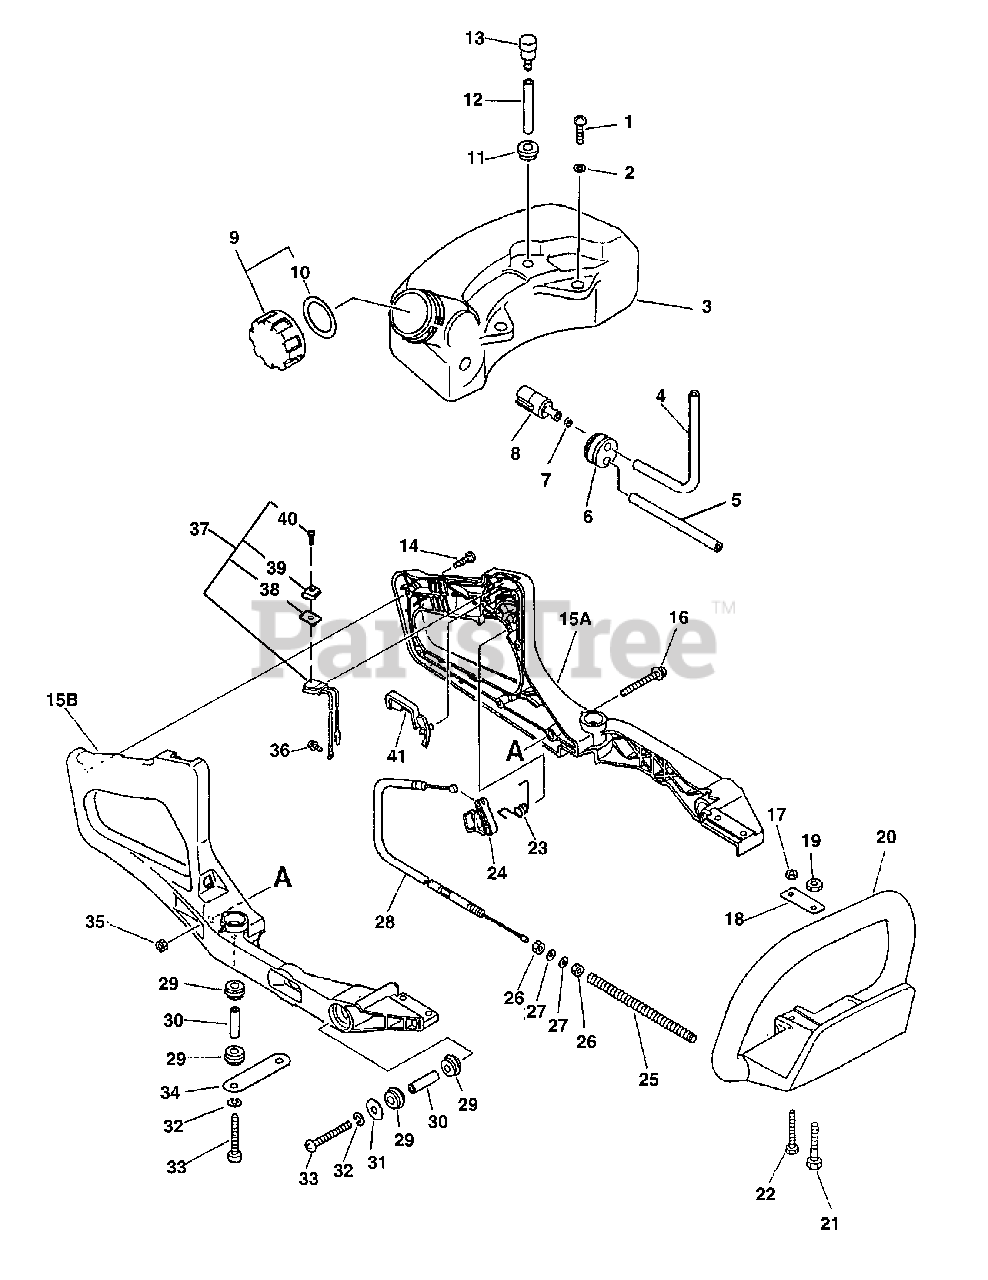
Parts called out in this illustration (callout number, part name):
1	SCREW 5×16
2	WASHER 5.5×12×0.8
3	TANK, FUEL
4	PIPE, FUEL
5	PIPE, FUEL 3x-5x-180
5	PIPE, FUEL
6	GROMMET
6	GROMMET, FUEL
7	CLIP 6 MM
8	FILTER, FUEL
9	CAP ASSY, FUEL
10	GASKET, FUEL CAP
11	GROMMET
12	PIPE, FUEL
13	VENT ASSY
14	SCREW 4×25
15A	HANDLE, REAR - LEFT
15B	HANDLE, REAR - RIGHT
16	SCREW 5×64
17	NUT M5
18	PLATE, EYE
19	NUT, HEX M6
20	HANDLE, SUPPORT
21	BOLT - 6×32
22	BOLT 5×35 SP
23	SPRING, TORSION
24	TRIGGER, THROTTLE
27	WASHER 6.5×11.5×0.8
28	CABLE, THROTTLE
30	SPACER
32	WASHER, SPRING 5
33	SCREW 5×40
34	PLATE, EYE
35	NUT M5
36	SCREW 5×10
37	IGNITION SWITCH ASSY
38	LABEL, SWITCH
39	KNOB, SWITCH - ORANGE
40	SCREW 3×10
41	LOCKOUT, THROTTLE
